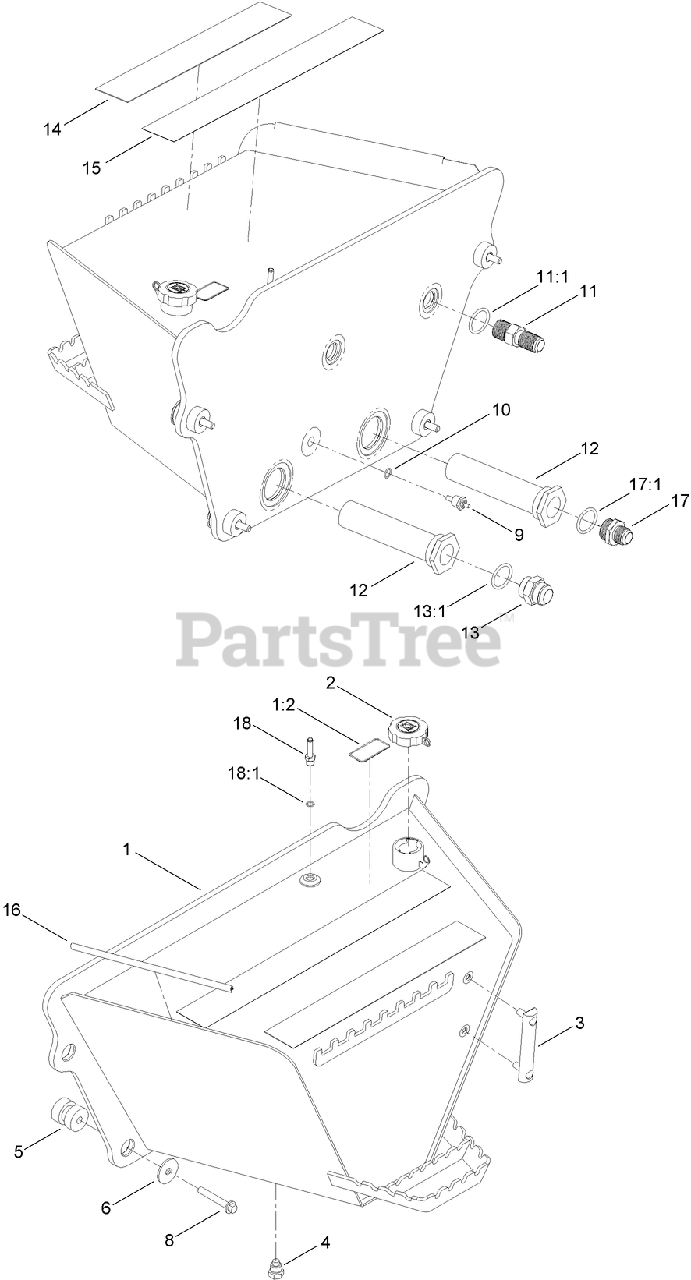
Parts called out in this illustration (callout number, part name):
1	HYD TANK AND DECAL ASM
1:2	DECAL-HYD FLUID
2	CAP-HYD FLUID (W/ LOCK)
3	GAUGE-LEVEL, FLUID (W/THERMOMETER)
4	PLUG-HEX, MAGNETIC
5	ISOLATOR-MOUNTING, UNIVERSAL
6	WASHER-FLAT
8	SCREW-HHF
9	SENSOR-SENDER, OIL/WATER TEMP
11:1	O-RING
12	STRAINER-MOUNTED, TANK
13	FITTING-STRAIGHT
13:1	O-RING
14	TAPE-ANTI SKID, LOWER STEP
15	STRIP-ANTI SKID
16	STRIP-SEAL
17	ADAPTER-STRAIGHT
17:1	O-RING
18	FITTING-STR
18:1	O-RING
